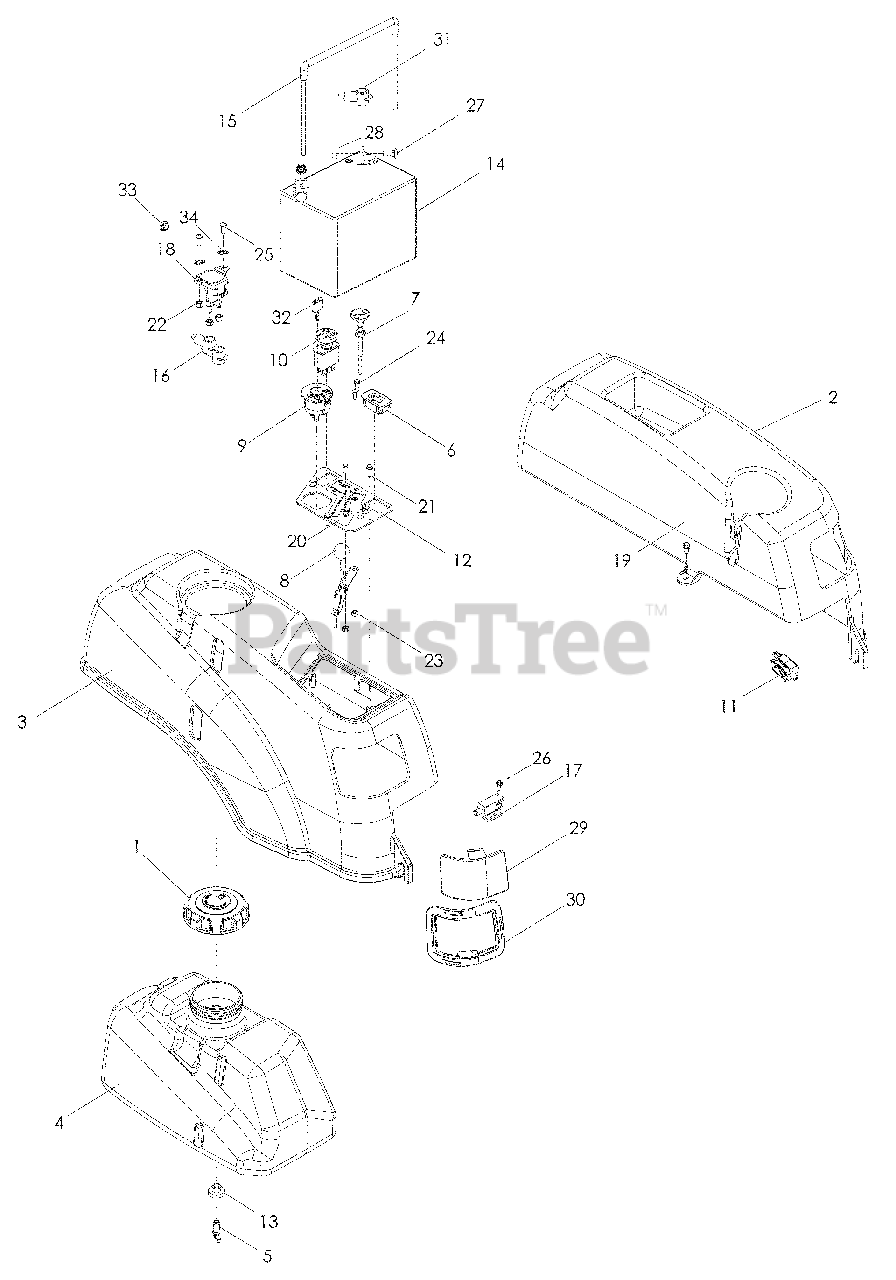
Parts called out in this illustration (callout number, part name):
2	FENDER, LT
3	FENDER, RT
4	TANK, FUEL
5	ELBOW, TANK
6	HOUR METER
7	CONTROL, CHOKE
8	CABLE, THROTTLE
9	SWITCH, IGNITION
10	SWITCH, CLUTCH
11	SWITCH, BRAKE
12	PLATE, CONTROL
13	GROMMET, RUBBER
14	BATTERY
15	TIE DOWN, BATTERY
16	COVER, TERMINAL
17	SWITCH, INTERLOCK
19	BOLT ¼-20 x ½ HWST
20	DECAL, CONSOLE
21	SCREW 10-24 x ½ SLT HD
22	NUT ¼-20 HEX NYLOC
23	NUT 10-24 HEX NYLOC
24	SCREW 10-12 x ¾ WSH HD
25	SCREW ¼-20 x 5/8 BTN SKT
26	SCREW 10-24 x 5/8 WSH HD
27	RHSNB 5/16-18 x ¾
28	NUT 5/16-18 HEX WHIZLK
29	LENS, LT
30	LENS RIM, LT
32	KEY, IGNITION
33	NUT ¼-20 HEX NYLOC THIN
34	WASHER ¼ ITLW
